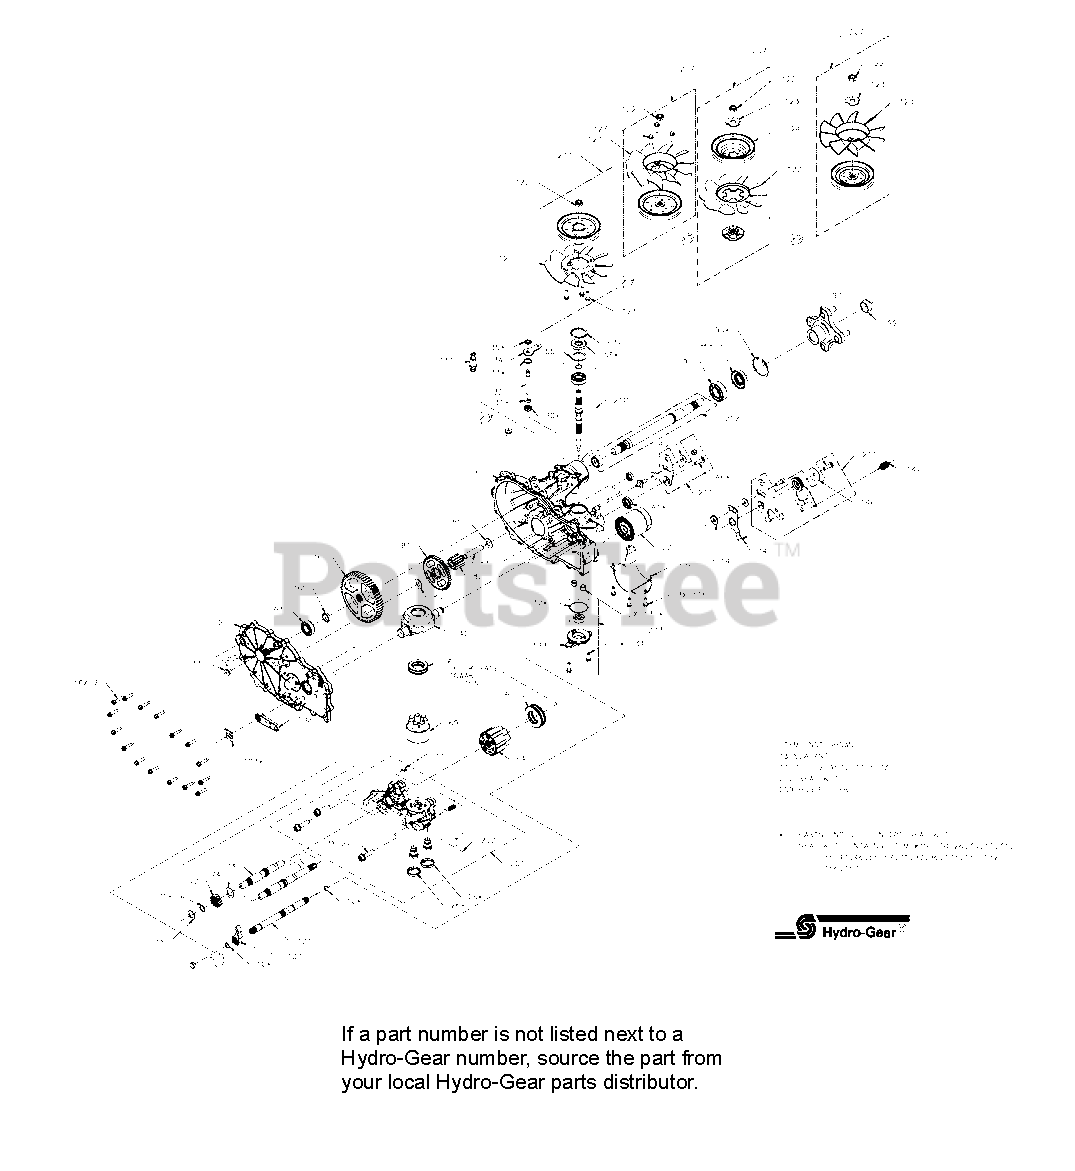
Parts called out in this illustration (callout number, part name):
1	KIT, HOUSING, MAIN, LH, CHRG, CNTL
11	PLUG 9/16-18 (METAL)
13	SEALANT
14	OIL, 20W50
22	PLATE, BYPASS
23	FILTER, OIL
26	SEAL, PLUG 1.250 x .250
27	HFHCS 3/8-16 x 1.5 (PATCH)
30	SEAL, LIP .375 x .75 x .25
31	RING, RET .375 EXTRNL
32	ROD, BYPASS
33	RING, RET .750 INTRNL
34	ARM, BYPASS
35	RING, RTNG .375 EXT
40	TRUNNION, SWASHPLATE
41	SEAL, LIP 12 x 32 x 7
45	WASHER .34 x .88 x .06
46	TWHCS 5/16-24 x 1.00 (PATCH)
55	WASHER 1.23 x 1.56 x .04
56	SEAL, LIP 17 x 40 x 7
57	RING, RETAINING
60	BEARING, THRUST
64	ASS'Y, CYLINDER BLOCK, 16cc
65	BRG, THRUST BALL 30 x 52 x 13
69	ASS'Y, BLOCK 7 PISTON
70	WASHER .63 x 1.0 x .05
71	RING, RETAINING_.625
72	GEAR, 16T
73	SHAFT, MOTOR
74	WASHER .72 x 1.16 x .04
80	WASHER .5 x 1.0 x .03
81	GEAR, 43T
82	GEAR, 11T
83	JACK SHAFT (PIN)
90	RING, RET 2.06 INT
91	GEAR, 54T
92	SPACER, .75 x 1.32 x .257
93	BEARING, BALL, .75 x 40 x 12
95	BRG, BALL 1.0 x 52 x 15 OPEN 6205M
96	SEAL, LIP 25 x 52 x 10 TC (GRAY)
97	KIT, HUB, 4 BOLT
99	NUT, HEX LOCK 3/4-16
100	PAWL, BRAKE
101	SHAFT, BRAKE
102	HANDLE, ACTUATING
103	CLIP, RETAINING
105	HFHCS 1/4-20 x .75
106	GUARD, FILTER, LH
111	FITTING, STR 9/16-18 SAE .5 BARB
122	NUT, HEX JAM 1/2-20 W/PATCH
123	HFHCS 1/4-20 x .875
130	TUBE, CONNECTING
131	GEROTOR ASSEMBLY (1.9 cc/rev)
132	O-RING, -137, 0.103 x 2.050
133	COVER, CHARGE PUMP
134	HFHCS 1/4-20 x .75
140	SPACER .320 x 1.005 x .179
141	ARM, NEUTRAL LEFT
142	SHCS 5/16-24 x 1 PATCH
146	WASHER, .343 x 1.500 x .062
147	SPRING, EXTNSN RTN-34-LBS
200	KIT, SEAL
201	KIT, CENTER SECTION, LH, CHRG
202	KIT, CHARGE RELIEF
203	KIT, CHARGE PUMP
207	KIT, FAN & PULLEY
209	HUB PULLER, 4 BOLT
210	KIT, INPUT SHAFT
211	KIT, RTN, CCW
212	KIT, SHAFT, AXLE
